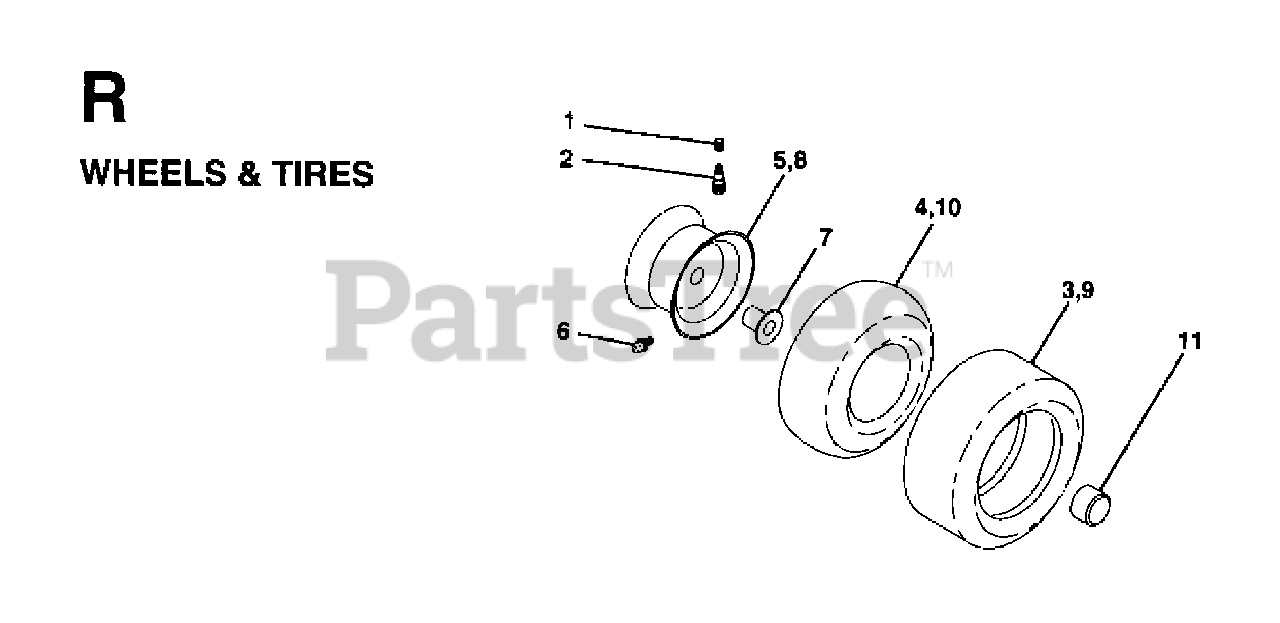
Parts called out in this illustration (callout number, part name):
1	VALVE CAP
2	VALVE STEM LT
3	TIRE HEAVY DUTY
4	TUBE.5.3/4.5/6
5	RIM ASM 6" FRONT SILVER
6	FITTING LT
7	BEARING T
8	RIM ASM 8" REAR SILVER
9	TIRE HEAVY DUTY
10	TUBE
11	CAP-HUB FRONT LT
